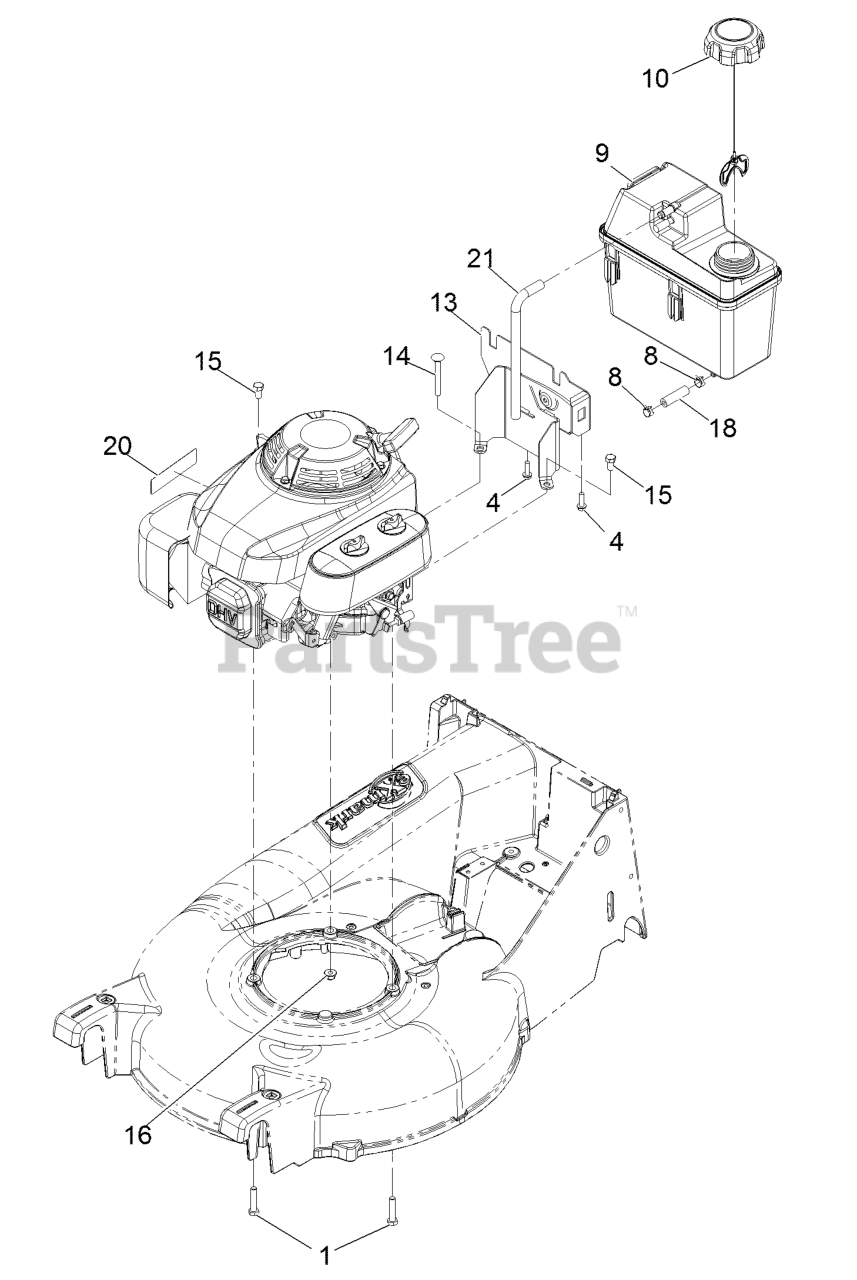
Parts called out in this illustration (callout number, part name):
1	SCREW-HH
4	SCREW-HWH
8	CLAMP-HOSE
9	TANK-FUEL
13	BRACKET ASM
14	SCREW-CARR
15	SCREW-HH
16	NUT-HF, NI
18	HOSE-FUEL
20	DECAL-ARRESTER, SPARK
21	HOSE-VENT, CANISTER
